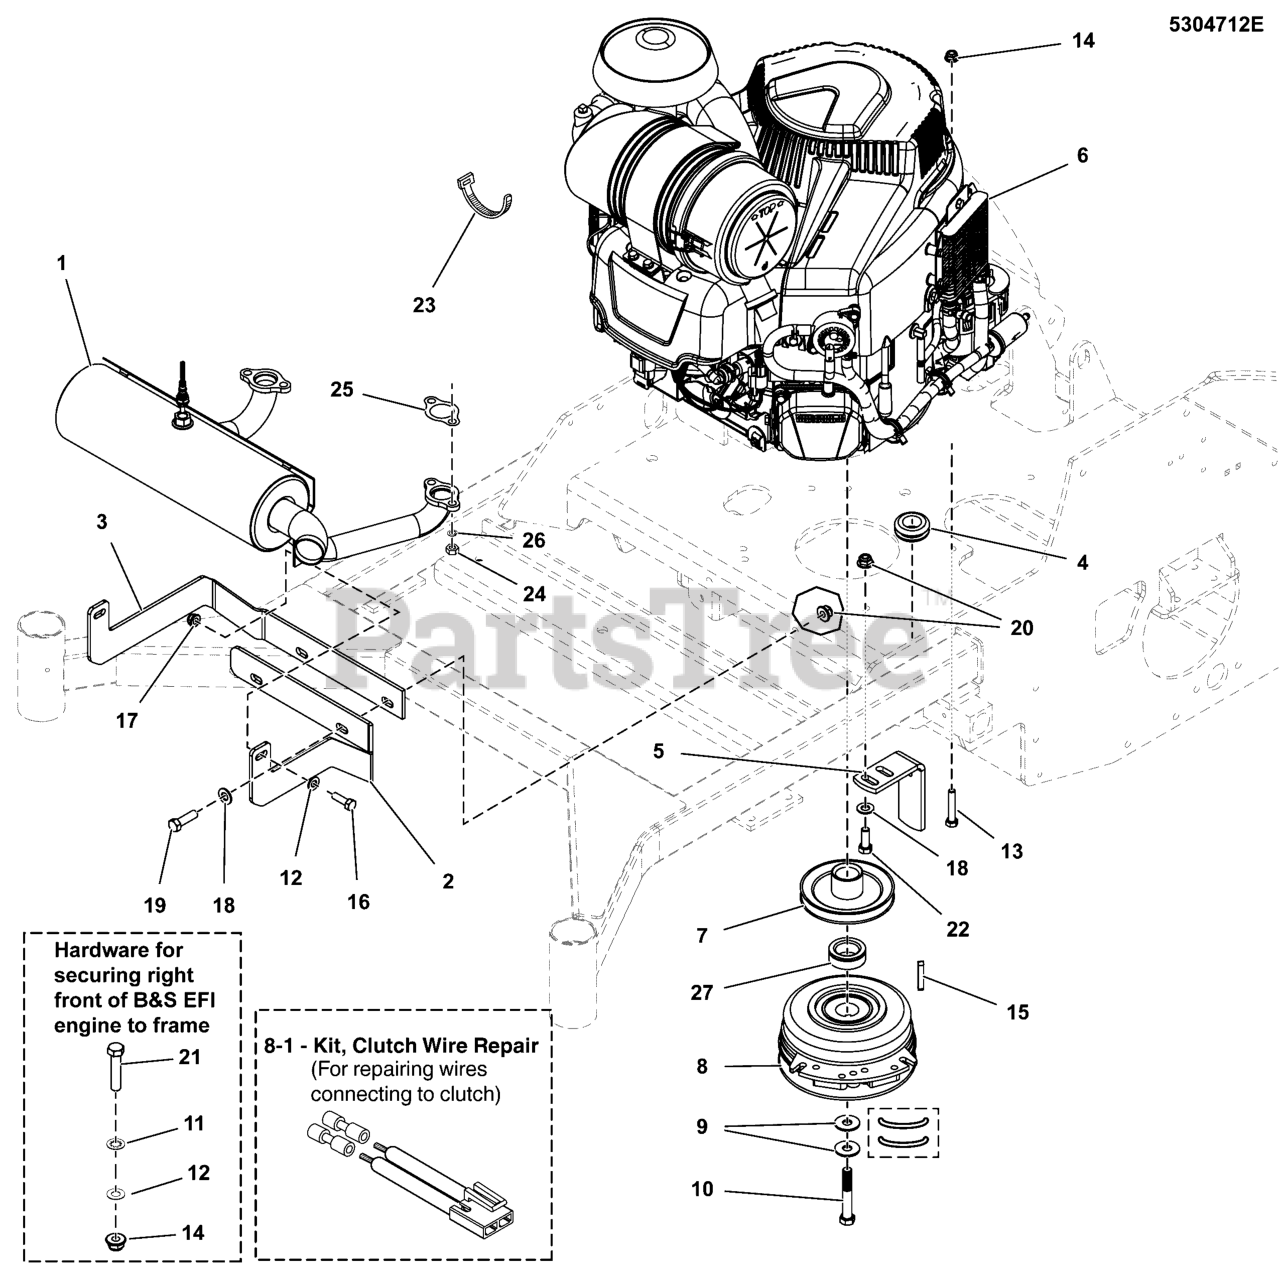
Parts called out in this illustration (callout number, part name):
1	MUFFLER, 26/28, B&S VANG, EFI TWR/WALK
2	PLATE, EXHAUST BRACKET LH - BLK
3	PLATE, EXHAUST BRACKET RH - BLK
4	GROMMET, 7/8"ID, 1/4" THICK STK
5	ANCHOR, CLUTCH - BLK
7	PULLEY, CRANKSHAFT, 1.1255 ID X 4.50 OD
8	CLUTCH WARNER 200 FT-LB 1.13 X 6.323
8-1	KIT, CLUTCH WIRE REPAIR
9	BELLEVILLE WASHER, 1.1875 X .442 X .098
10	BOLT, CRANKSHAFT, 7/16 X 2-3/4, PATCH, CZ
11	WASHER, 5/16" Internal Tooth Lock
12	WASHER, 5/16" SAE
13	BOLT, 5/16-24 X 1-3/4, GD8, PHOS
14	NUT, 5/16-24, TOP LOCK FLANGE, GD8 PHOS
15	KEY, 1/4" SQ. X 1-1/4
16	BOLT, 5/16-18 X 1" GRD5 YZ
17	NUT, 5/16-1/8, HEX, CNTR LK, ZINC PHOS/OIL
18	WASHER, 3/8 SAE
19	BOLT, 3/8-16 X 1-1/4" GD5 CZ
20	NUT, 3/8 - 16 HEX NYLOCK FLANGE
21	BOLT, 5/16-24 X 1-1/2, GD8, PHOS
22	BOLT, 3/8-16 X 1" GD5 CZ
23	TIE,SELF-LOCKING, 24"
24	NUT, HEX, M8-1.25, CZ, GD 8.8
25	GASKET, EXHAUST
26	WASHER, Light Lock, 5/16
27	SPACER, 1.13 X 1.75 X .63
